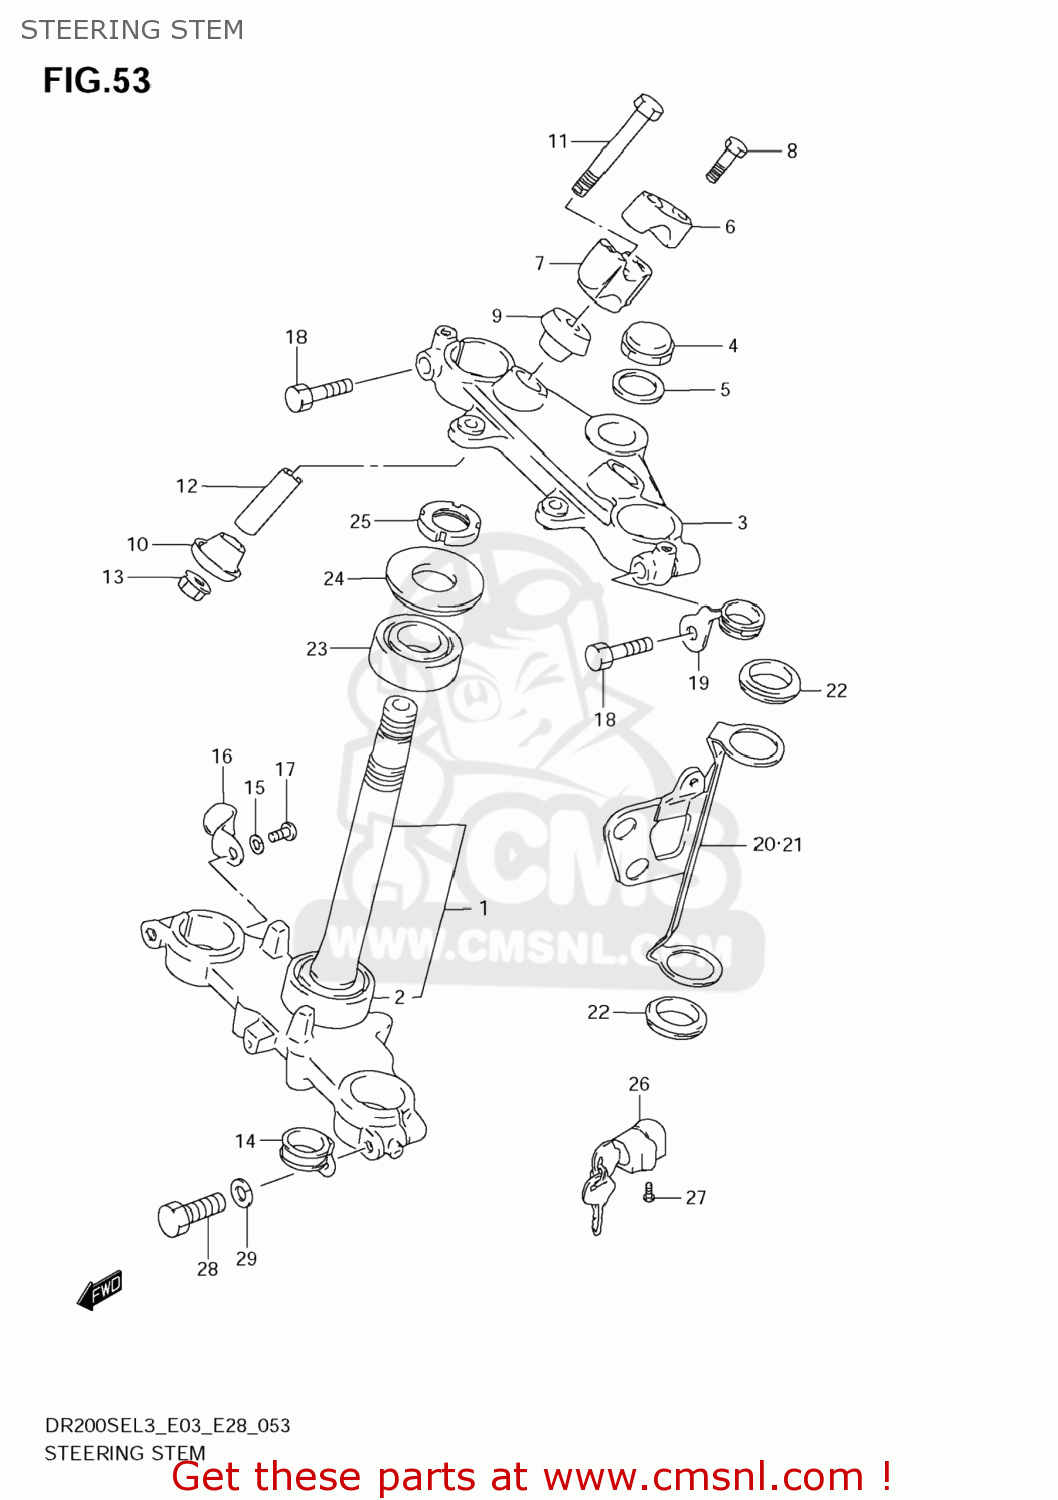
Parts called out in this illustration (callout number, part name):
1	STEM,STEERING
2	BEARING(30X55X17)
3	HEAD,STEERING STEM
4	NUT,CAP
5	WASHER
6	HOLDER,HANDLE UPR
7	HOLDER,HANDLEBAR LWR
8	BOLT
9	RUBBER,HANDLE HOLDER
10	CUSHION,RUBBER UNDER
11	BOLT,HANDLE HOLDER(10X70)
12	SPACER
13	NUT
14	CLIP,LOWER
15	WASHER,LOCK
16	CLIP
17	SCREW
18	BOLT
19	CLIP
20	BRACKET,HEADLAMP,R
21	BRACKET,HEADLAMP,L
22	CUSHION,HEADLAMP HSG BRACKET
23	BEARING(25X47X15)
24	SEAL,STEERING UPR DUST
25	NUT,STEERING
26	LOCK SET,STEERING
27	SCREW
28	BOLT,INNER TUBE FITTING
29	WASHER,LOCK
